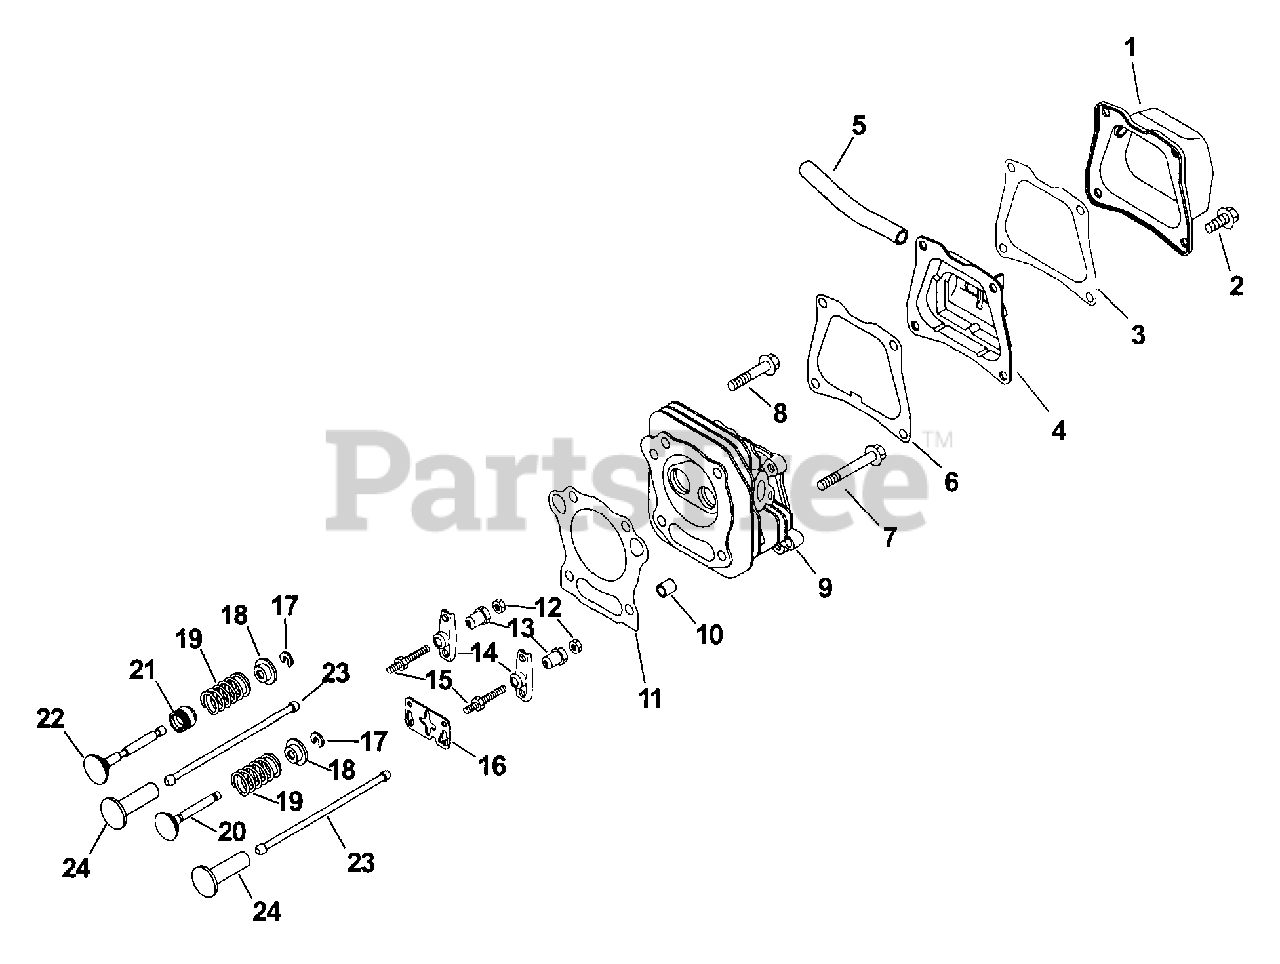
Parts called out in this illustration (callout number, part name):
1	COVER, VALVE
3	GASKET, VALVE COVER
4	BREATHER ASSEMBLY
5	HOSE, BREATHER
6	GASKET, BREATHER
7	SCREW, CYL HEAD
8	SCREW, CYL HEAD
9	CYLINDER HEAD-CSG-USE 63 318 08-S
10	PIN, DOWEL
11	GASKET, CYL HEAD -USE 63 041 46-S
13	PIVOT, ROCKER ARM
14	ARM, ROCKER
15	SCREW, VALVE ADJ
16	PLATE,GUIDE
17	VALVE, COTTER
18	CAP,VALVE SPRING
19	SPRING, VALVE
20	VALVE, INTAKE
21	SEAL, VALVE STEM
22	VALVE, EXHAUST
24	LIFTER, VALVE
